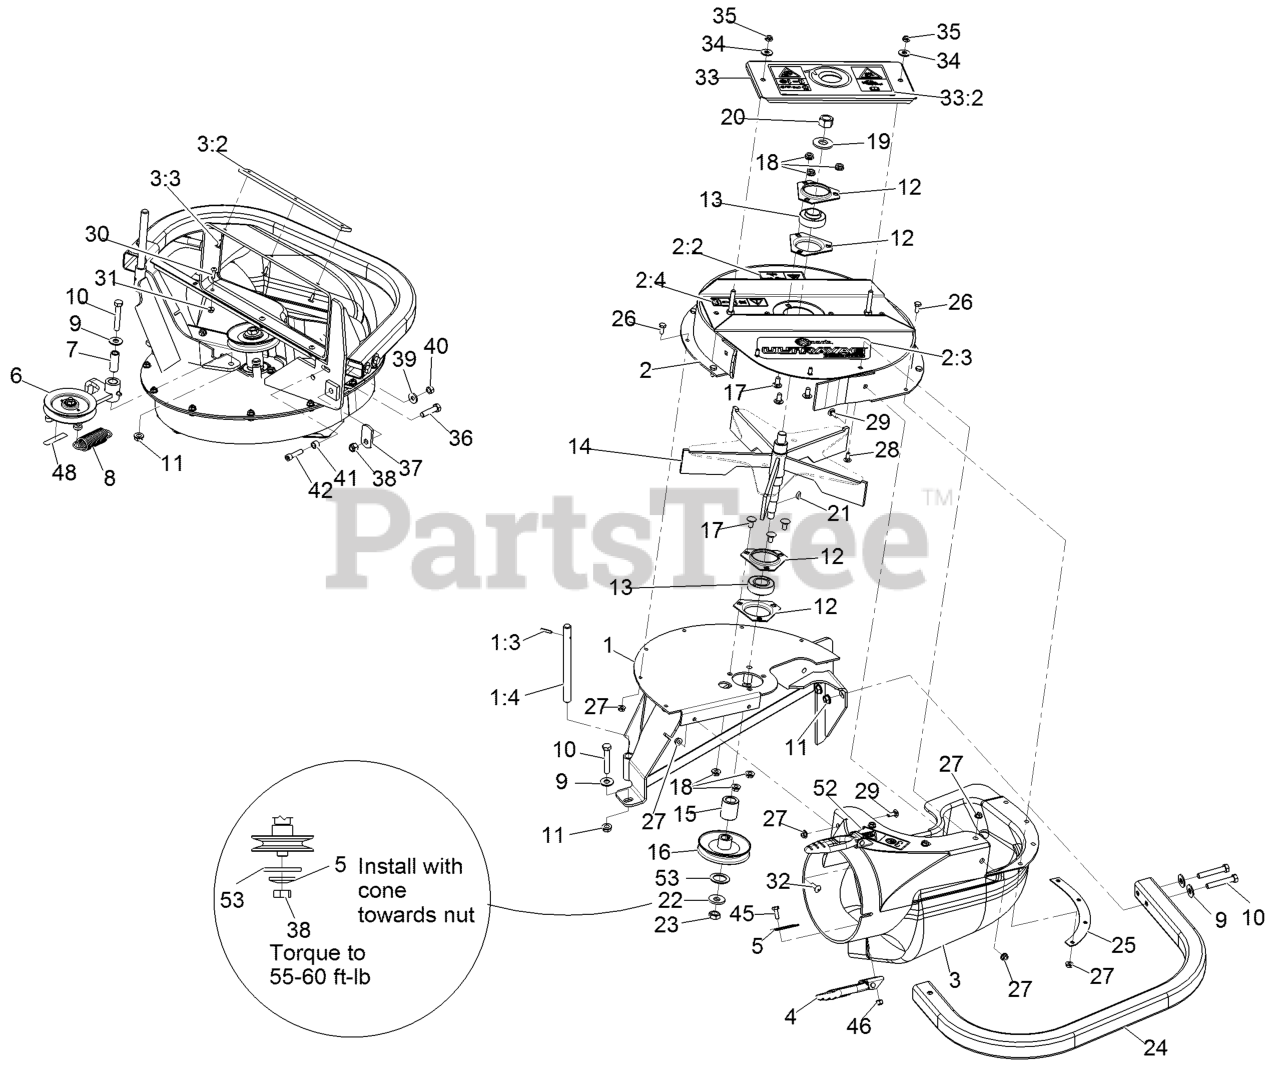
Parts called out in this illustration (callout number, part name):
1	Wld,Frame Lg Blower
1:3	Rollpin 3/16 X 7/8
1:4	Shaft-Catcher, Grass
2	ASM-Upper Housing Large
2:2	Decal-Warning, Traction
2:3	Decal-Ultravac X-Series
2:4	Decal-Missing, Cover
3	Asm, Blower Chute
3:2	Plate, Reinforcement
4	Latch-Rubber
5	Plate-Backing
7	Bushing
9	Washer-3/8 Std
10	Screw-HH 3/8-16 X 2 1/4
11	Nut-Whizlock 3/8-16
12	Housing-Flange
13	Bearing
14	Impeller
17	Bolt-Carriage 5/16-18 X 5/8
18	Nut-Whizlock 5/16-18
19	Washer-Spring Disc 5/8
20	Nut-Hex 5/8-18
21	Key-Woodruff 3/16 X 5/8
22	Washer-Spring Disc 1/2
23	Nut-Jam 1/2-20
25	Plate-Backing, Blower
26	Screw-HH 1/4-20 X 5/8
27	Nut-Whizlock 1/4-20
28	Bolt-Carriage 1/4-20 X 5/8
29	Bolt-Carriage 1/4-20 X 3/4
30	Screw-Truss Head #10-24 X 3/4
31	Nut-Whizlock #10-24
32	Screw-PPH 1/4-20 X 3/4
33	Cover, Bearing W/Decal
33	Cover, Bearing With Decal
33:2	Decal, Warning
34	Washer-5/16 Std
35	Nut-Nyloc 5/16-18 Thin
36	Screw-HH 3/8-16 X 1 1/2
37	Latch-Catcher, Grass
38	Nut-Nyloc 3/8-16
39	Washer-Spring Disc 5/16
40	Nut-Hex 5/16-18
41	Bushing
42	Screw-Sh 5/16-18 X 1 1/4
45	Screw-HH 1/4-20 X 3/4
46	Nut-Nyloc 1/4-20
48	Decal-Warning
52	Decal-Warning
